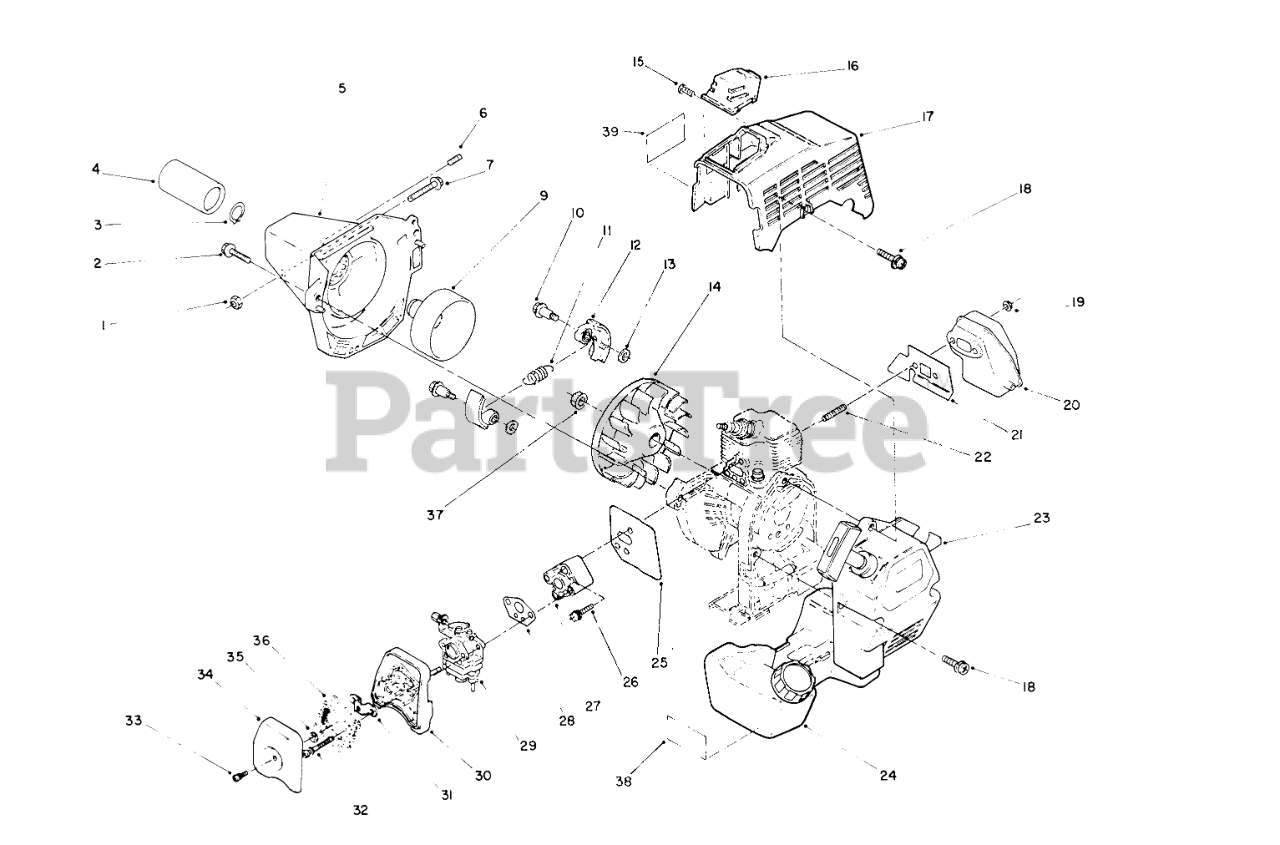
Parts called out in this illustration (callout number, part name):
2	BOLT AND WASHER
3	SNAPRING
4	Spacer
5	Housing-Clutch
6	SETSCREW
7	Screw/Washer
9	CLUTCH DRUM
10	CLUTCH BOLT
11	Spring
12	SHOE, CLUTCH
13	WASHER
14	Fan
15	SCREW & WASHER
16	SPARK PLUG GUARD
17	TOP SHIELD
18	SCREW & WASHER
19	MUFFLER FLANGE NUT
20	MUFFLER
21	Gasket-Muffler
22	MUFFLER STUD
23	Starter-Recoil
24	Fuel Tank Assembly
25	INSULATOR GASKET
26	SCREW & WASHER
27	INSULATOR
28	CARBURETOR GASKET
29	Carburator Assembly
30	CLEANER CASE
31	BRACKET
32	SCREW W/ WASHER
33	SCREW & WASHERE
34	CLEANER COVER
36	CLEANER ELEMENT
38	Plate
39	DECAL-SURFACE, HOT
